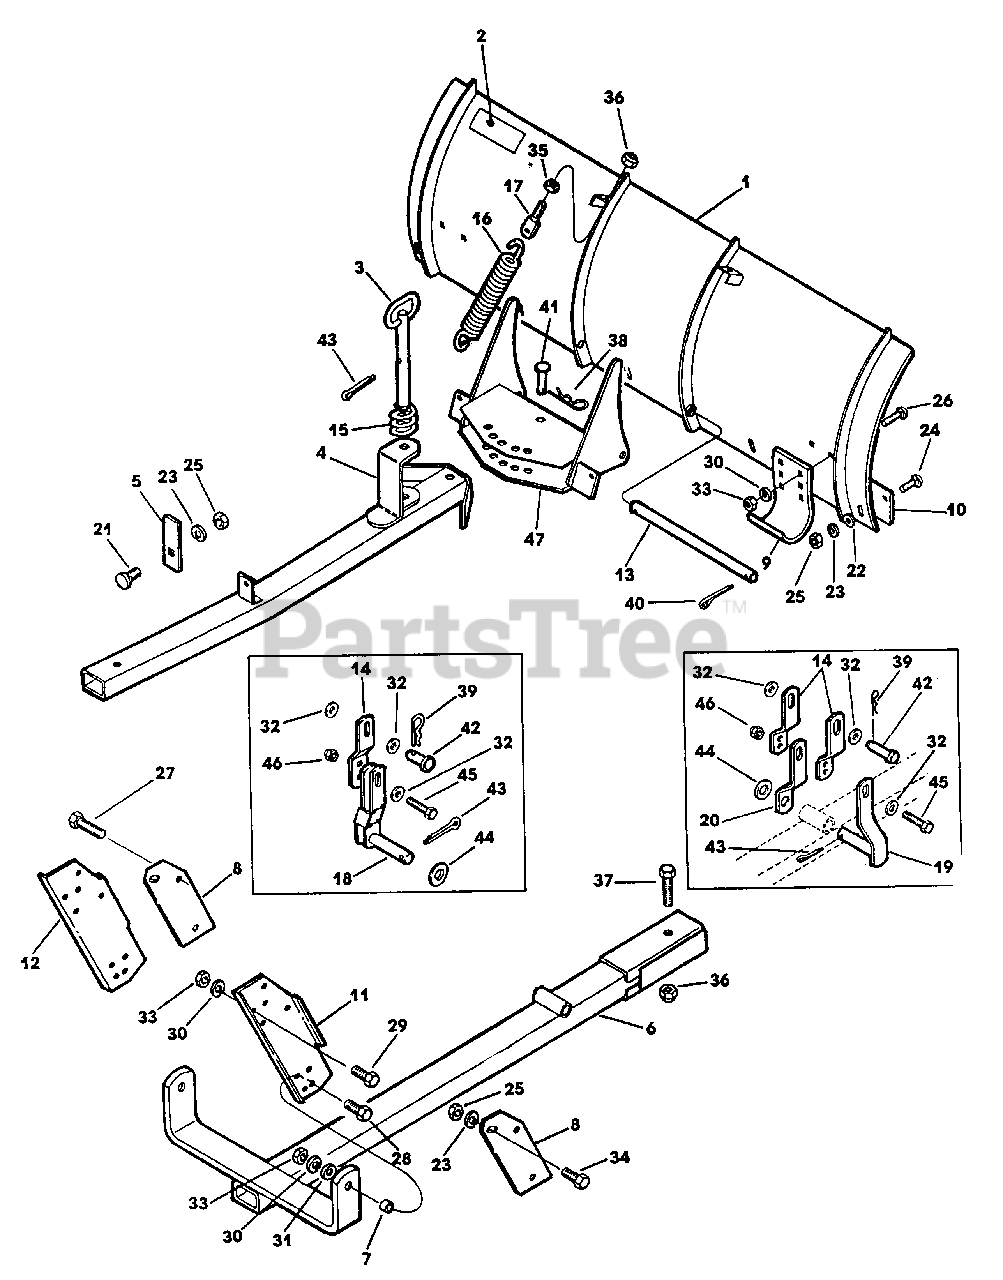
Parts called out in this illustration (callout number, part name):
1	Snow Blade Assembly w/Decal
2	Decal-Warning
3	Hitch Pin Assembly
4	Front Frame Assembly
5	Frame Stop
6	Rear Frame Assembly
7	Pivot Spacer
8	Hanger Plate (Lawn Tractor Only)
9	Shoe
10	Scraper Blade
11	Mounting Bracket-R.H. (Yard Tractor Only)
12	Mounting Bracket-L.H. (Yard Tractor Only)
13	Trip Pin
14	Link-Reversing
15	Spring-Hitch Pin
16	Spring-Blade
17	Spring Adjusting Bolt
18	Lift Link Assembly
19	Lift Link Assembly
20	Lift Strap
21	Bolt, Wafer Head
22	Washer, Flat
23	Washer, Lock
24	Bolt, Carriage
25	Nut, Hex
26	Bolt, Carriage
27	Cap Screw, Hex Hd
28	Cap Screw, Hex Hd
29	Cap Screw, Hex Hd
30	Washer, Lock
31	Washer, Flat
32	Washer, Flat
33	Nut, Hex
34	Cap Screw, Hex Hd
35	Nut,Hex Jam
36	Nut, Hex Cone Lock
37	Cap Screw, Hex Hd
38	Spring Clip
39	Spring Clip
40	Pin, Cotter
41	Clevis Pin
42	Clevis Pin
43	Pin, Cotter
44	Washer, Flat
45	Cap Screw, Hex Hd
46	Nut, Hex Cone Lock
47	Trip Plate Assembly
